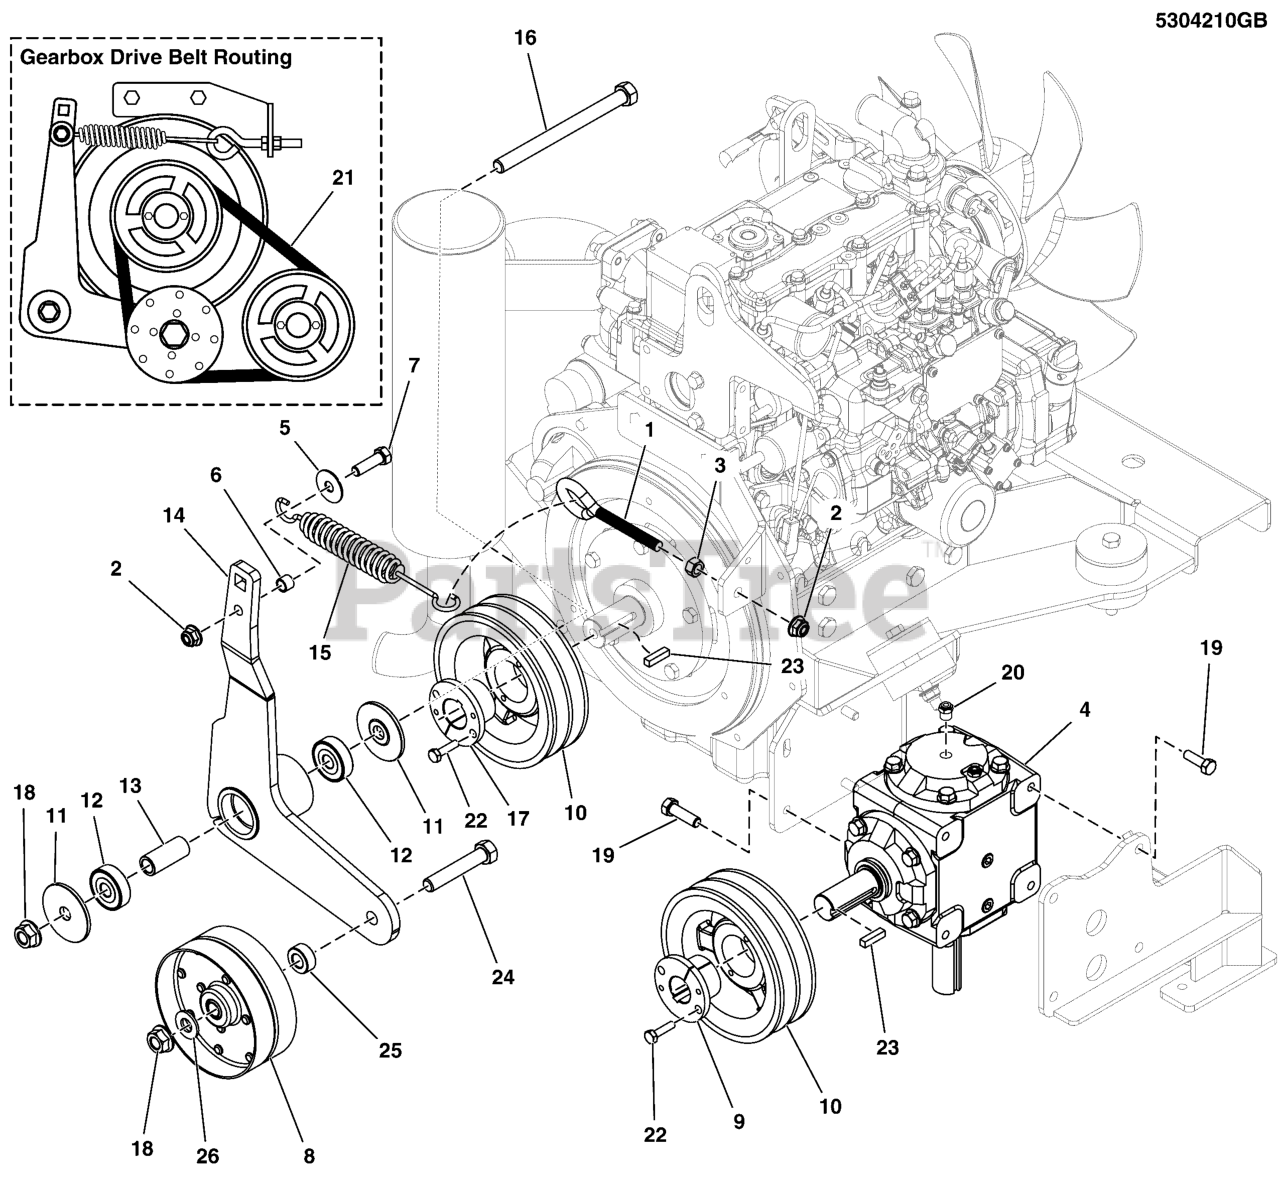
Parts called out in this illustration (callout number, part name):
1	EYE BOLT,3/8-16X4.13,2.33THRD,.75EYE,CZ
2	NUT, 3/8-16 HEX NYLOCK FLANGE
3	NUT, 3/8-16 HEX SERRATED FLANGE
4	GEAR BOX, RIGHT ANGLE, MODEL 215 SPECIAL
5	WASHER-3/8 FENDER
6	SPACER, .38 X .50 X .38, CZ
7	BOLT, 3/8-16 X 1-1/4" GD5 CZ
8	PULLEY, FLAT IDLER, 5"OD X 2" W X .5 ID
9	BUSHING, TAPERED HUB
10	PULLEY, DOUBLE, DH4600, 5.95 OD TAPERED
11	SPACER, IDLER ARM, 1/2 X 2.25
12	BEARING, 6203-1/2", SEALED
13	SPACER, .510 X .750 X 1.749, CZ
14	ARM, Idler
15	SPRING-EXT, 1.04 ODX6.935LGX.148WR, BLK
16	BOLT, 1/2-13 X 4-1/2 GD5 CZ
17	TAPER LOCK BUSHING, HQ-1-1/8"
18	NUT, Hex Flange, Nylock, 1/2-13
19	BOLT, 3/8-16 X 3/4" GD5 CZ
20	PRESSURE RELIEF VALVE, #410696
21	BELT, B-SEC, DOUBLE, BANDED, 41.75" EL
22	BOLT, 1/4-20 X 1" GD5 CZ
23	KEY, 1/4 SQ X 1-1/4
24	BOLT, 1/2-13 X 2-3/4 GD5 CZ
25	SPACER, .52 X 1.00 X .44, CZ
26	WASHER, 1/2 SAE
